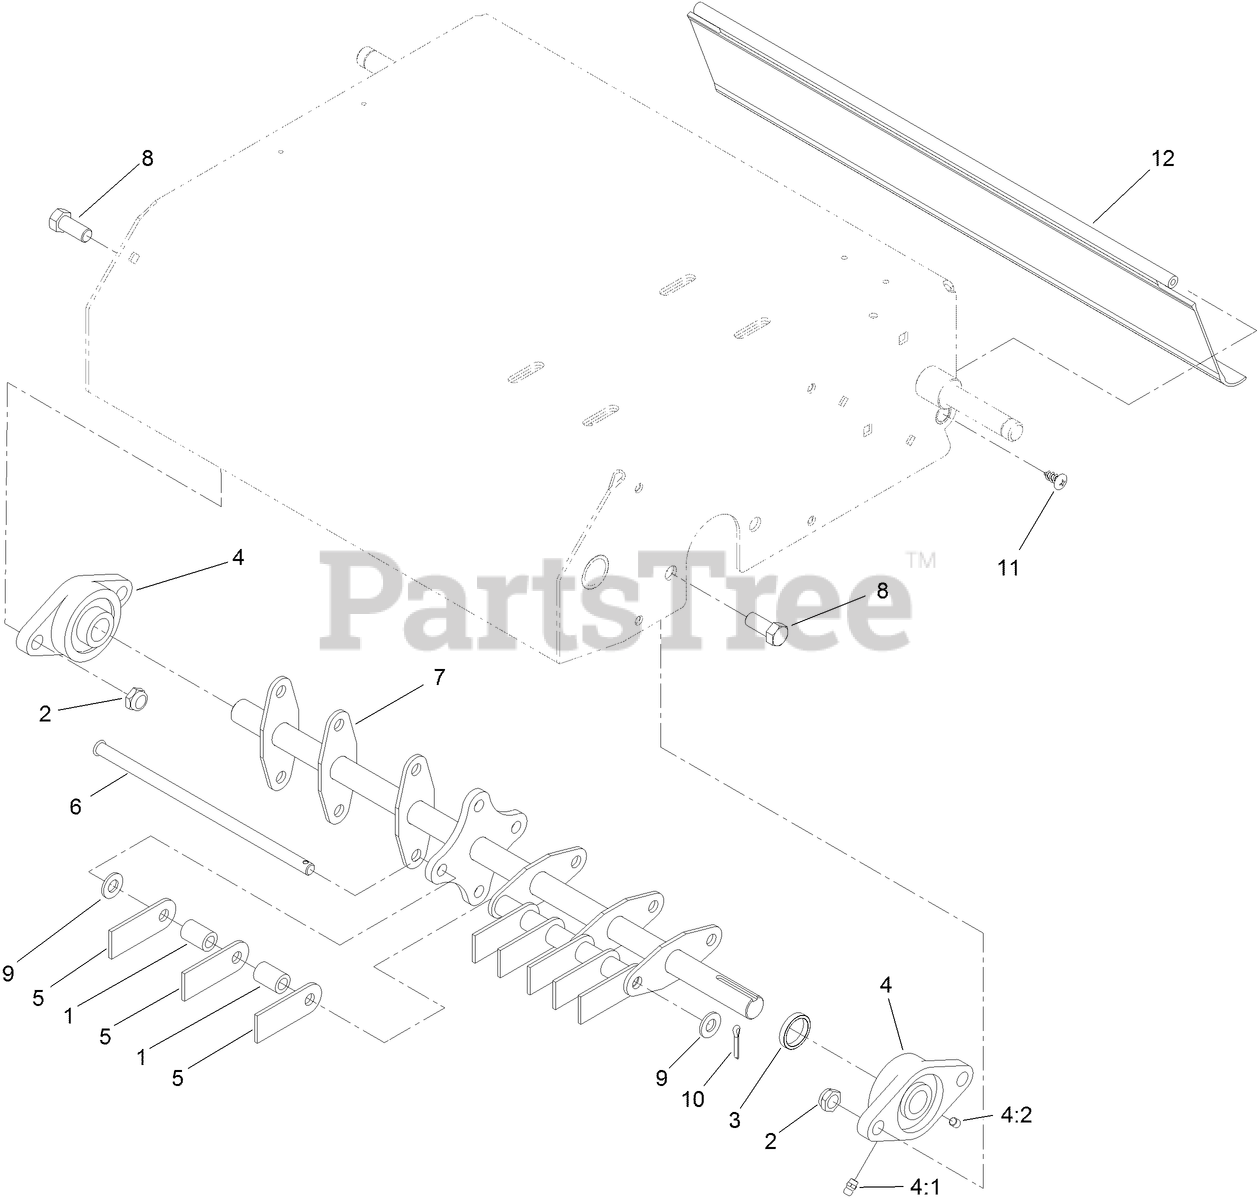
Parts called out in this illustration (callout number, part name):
1	SPACER
2	NUT-LOCK, NI
3	COLLAR
4	BEARING-FLANGE
4:1	FITTING-STRAIGHT
4:2	SCREW-SET, HSH
5	BLADE-FLAIL
6	SHAFT-SATELLITE
7	SHAFT-RAKE
8	SCREW-HH
9	WASHER-FLAT
10	PIN-COTTER
11	SCREW-PTH
12	SHIELD-TRAILING
